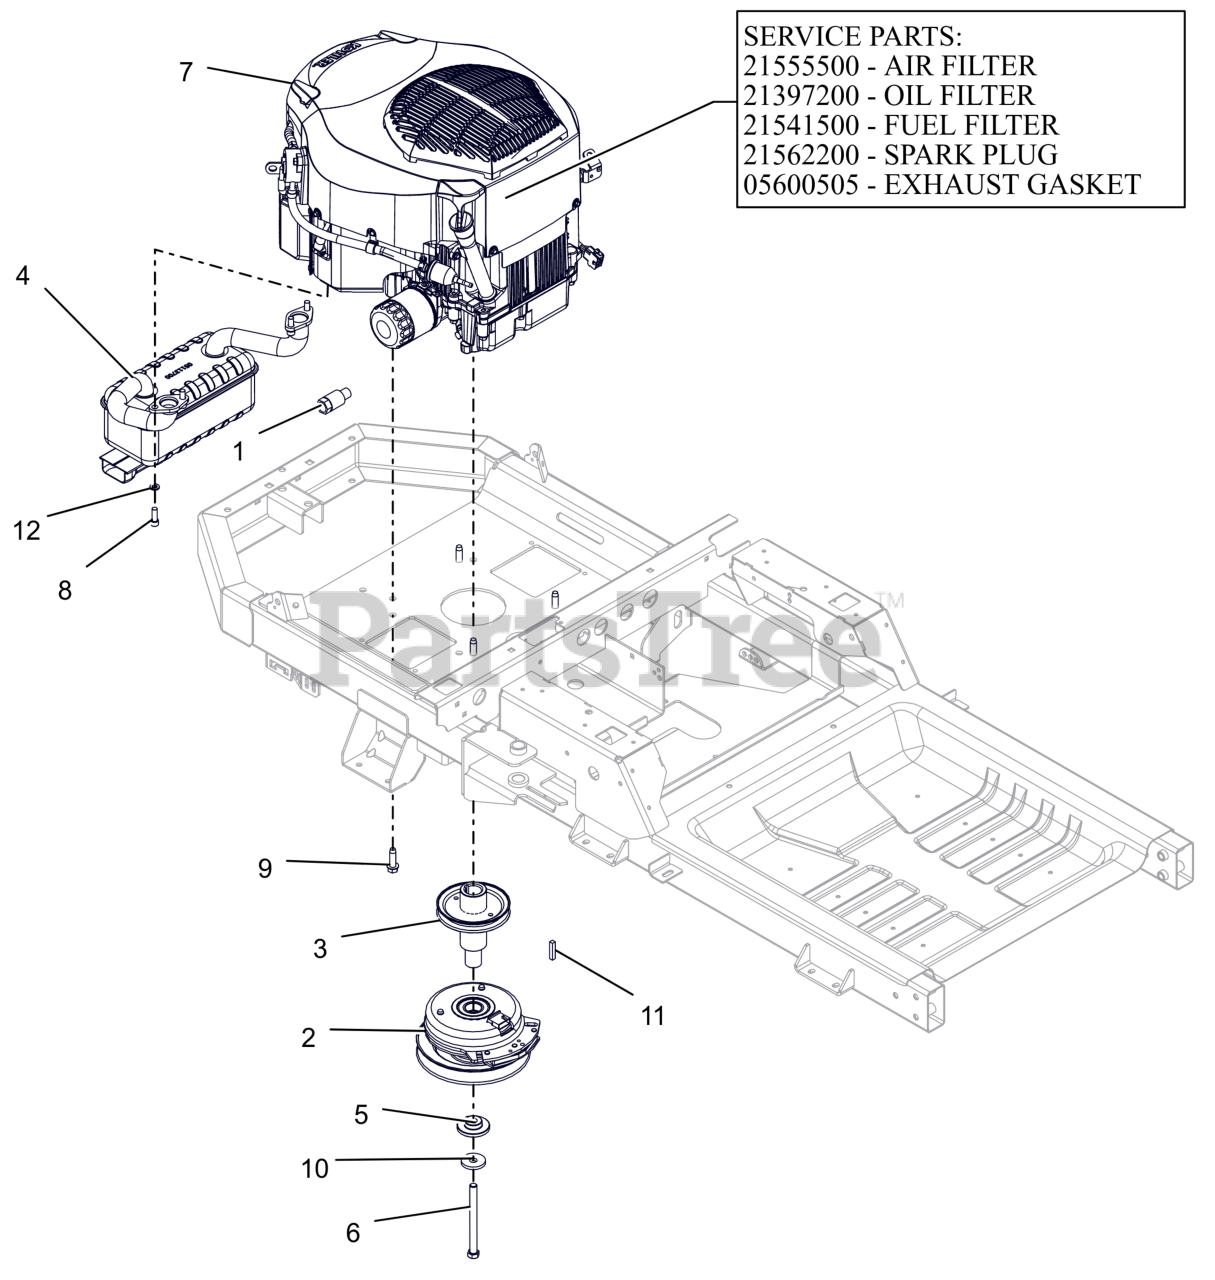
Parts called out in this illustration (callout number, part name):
1	DRAIN, OIL
2	CLUTCH,105FTLB MONOPOLE 6.83"
3	WLDMT, DRIVE SHEAVE (LG XL)CZC
4	MUFFLER, KOHLER
5	BSHG-FLG .469X1.06X.574X2.0
6	BLT-HEX.438-20X5 GR8 YZ NYTORQ
7	ENGINE, KOHLER 22HP TWIN
7	AIR CLEANER, KOHLER
7	FILTER, OIL - KOH CV20
7	FILTER, FUEL
7	PLUG, SPARK (RFI)
7	GASKET, MUFFLER COURAGE TWIN
8	SCR-CAP .31-18X.88 S/HD G8 ZCC
9	SCR,TAP .375-16X1.25HWH TR ZCC
10	WASHER, 7/16" SPRING DISK
11	KEY-SQ .25 X 1.25 X .25 SAE
12	WSHR,LK-REG .312X.078 ZCC
